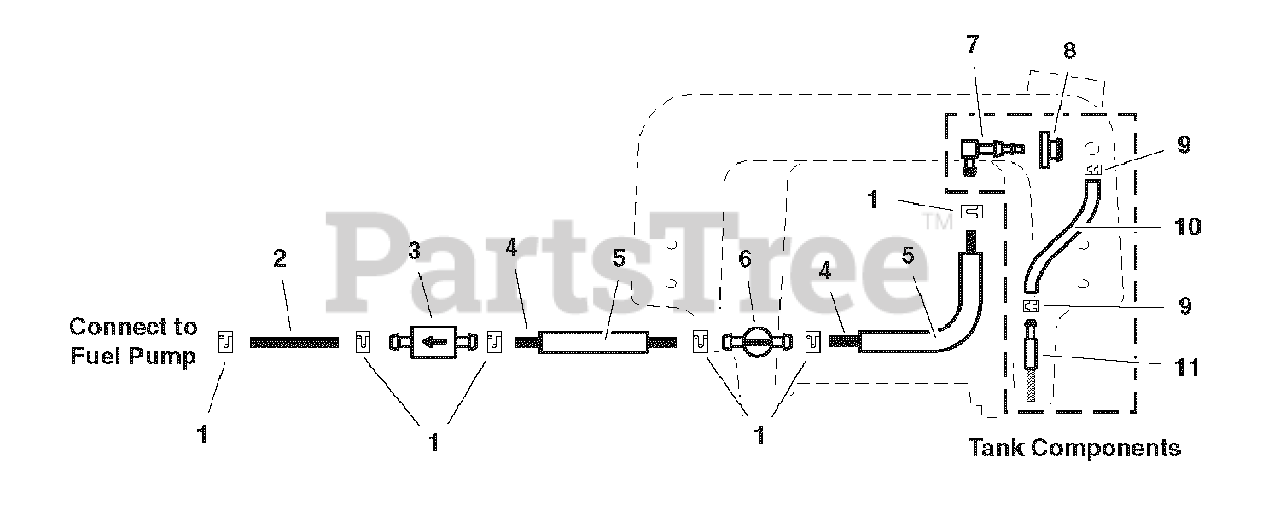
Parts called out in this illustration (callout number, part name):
1	CLAMP, Hose 1/4"
2	HOSE, 7 (supplied with engine)
3	FUEL FILTER
4	HOSE, 19-1/2"
5	WIRE LOOM, 18"
6	VALVE, FUel Shut-Off
7	ELBOW FITTING
8	GROMMET
9	HOSE CLAMP
10	HOSE, 20"
11	SCREEN FITTING
